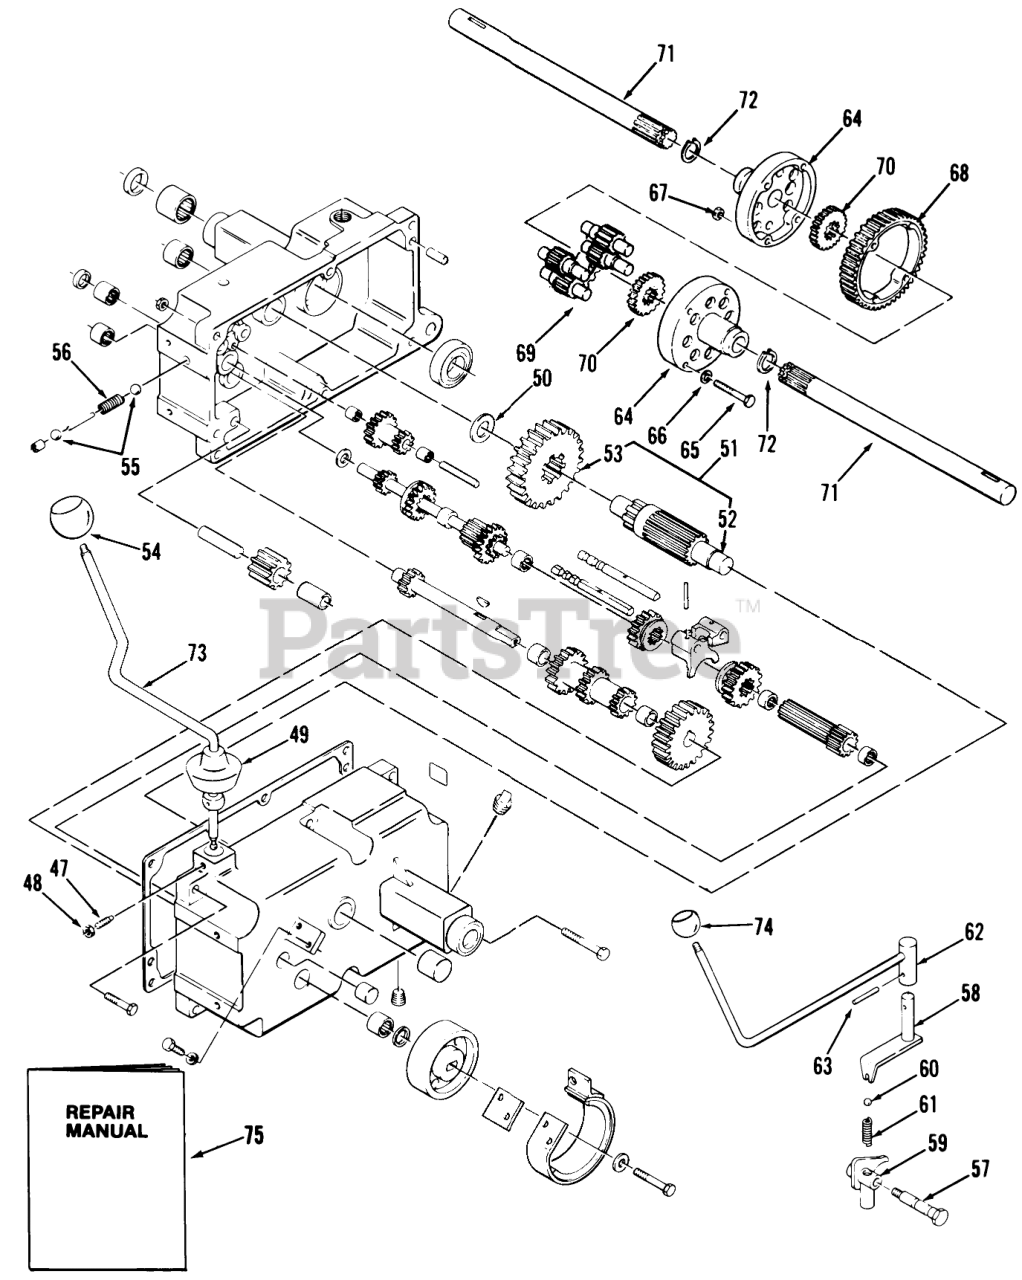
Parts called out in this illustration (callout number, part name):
47	SETSCREW
48	Nut
49	COVER-DUST
50	WASHER-THRUST
51	GEAR ASM
52	PINION SHAFT
55	BALL-DETENT
56	SPRING-SHIFT STOP
57	BOLT-DETENT
58	SHIFT ASM
59	Shift Fork
60	BALL-DETENT
61	SPRING-SHIFT STOP
62	Shift Lever HI-Low Range
63	PIN-SPIROL
64	CASE-DIFFERENTIAL
65	Bolt 3/8-16 x 3 1/4
66	WASHER
68	DIFFERENTIAL BULL GR
69	GEAR-PINION, 11T
70	AXLE GEAR
71	AXLE-REAR
72	Snap Ring
73	Gear Shift Lever
74	Knob
75	MANUAL
